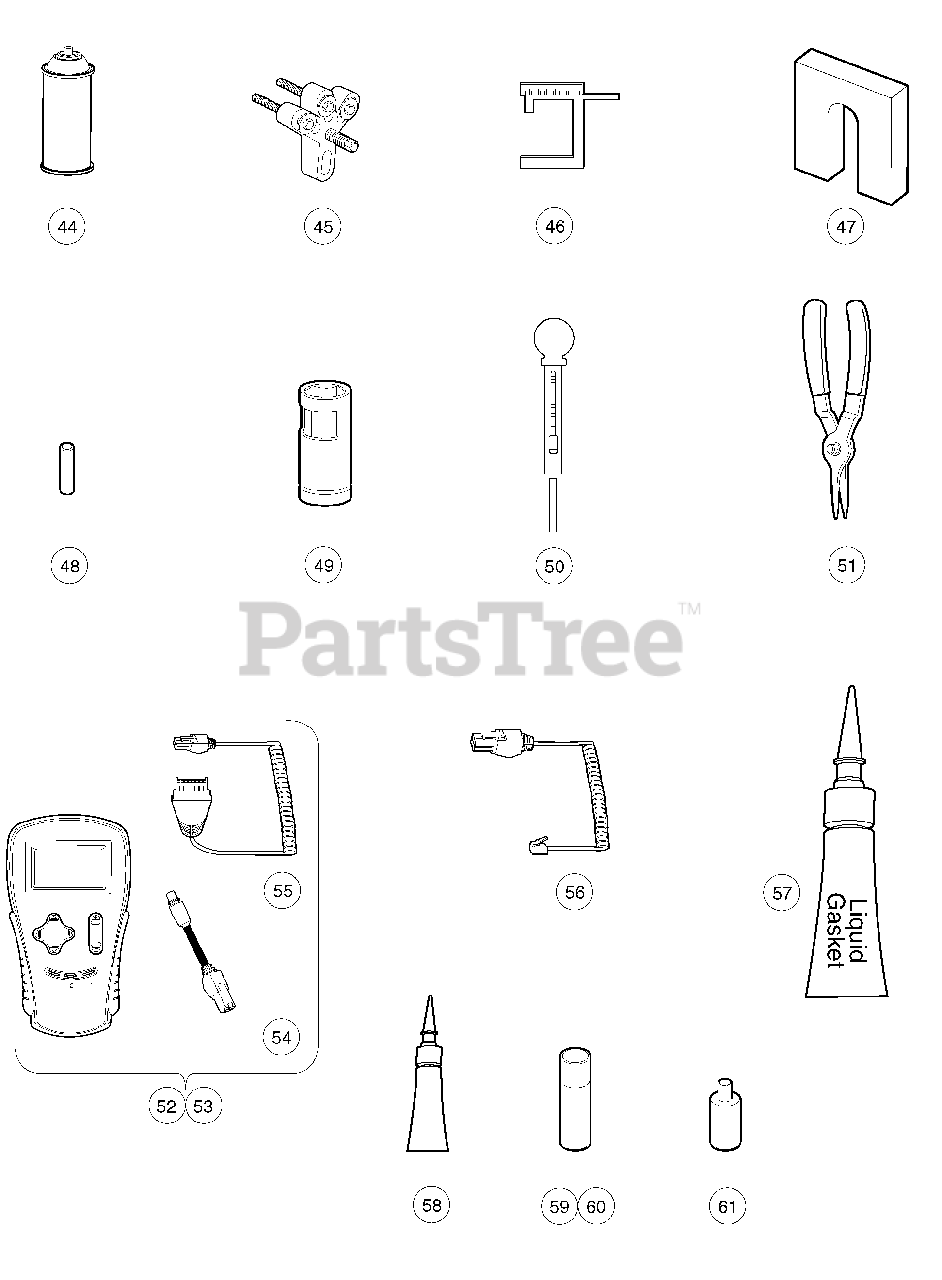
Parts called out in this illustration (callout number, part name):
44	Dry Moly Lubricant
45	Flywheel Puller Kit
46	Gauge, Carburetor Float Level
47	Gear Yoke
48	Governor Shaft Installation Tool
49	Hydraulic Brake Adjuster
50	Hydrometer
51	Internal Retaining Ring Pliers
52	IQ Display Module (IQDM) Kit (IQ System and IQ Plus vehicles)
53	IQ Display Module (IQDM-P) Kit (IQ System and IQ Plus vehicles)
54	Adaptor, Cable
55	IQDM Series 2 Cable
56	IQDM Series 1 Cable (replacement)
57	Liquid Gasket (transaxle case)
58	Moly-Teflon Lubricant (4-oz. (113-gram) tube)
59	Paint, Touch-Up - Beige
59	Paint, Touch-Up - Black
59	Paint, Touch-Up - Burgundy
59	Paint, Touch-Up - Classic Blue (Navy)
59	Paint, Touch-Up - Dark Gray
59	Paint, Touch-Up - Dark Green
59	Paint, Touch-Up - Gray
59	Paint, Touch-Up - Red
59	Paint, Touch-Up - Royal Blue (Pacific Blue)
59	Paint, Touch-Up - White
60	Paint, Precedent Underbody - Gray
61	Paint Pen, Touch-Up, Precedent Underbody - Black
